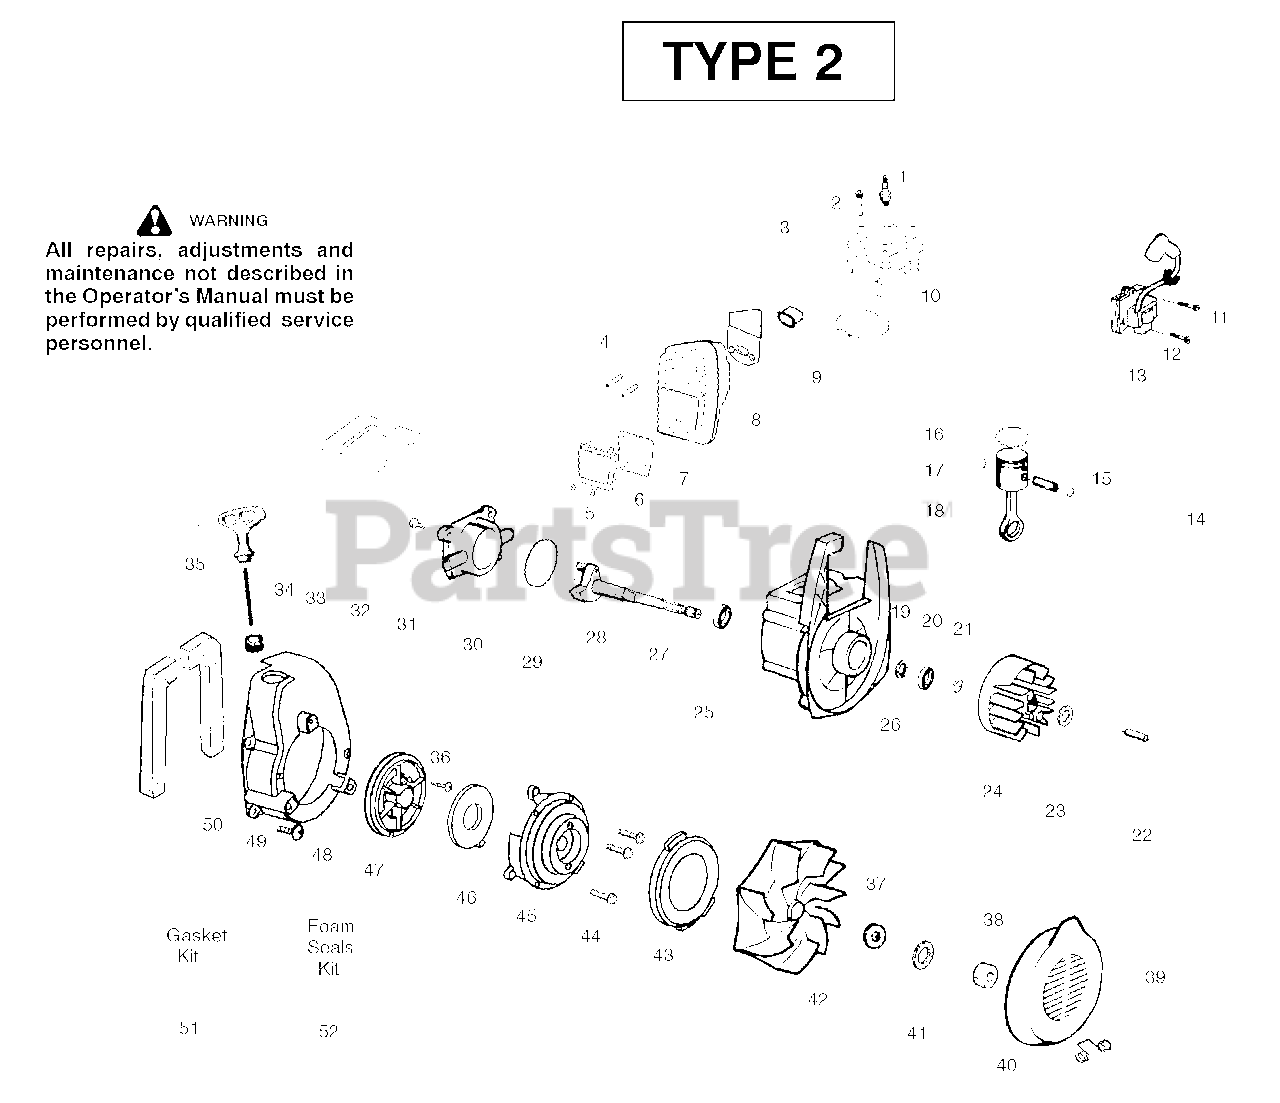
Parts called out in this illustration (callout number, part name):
1	Spark Plug (RCJ-6Y)
3	Insulator-Heat
4	Screw-Muffler-Internal
6	Kit-Spark Screen
7	Kit-Muffler
8	Gasket-Baffle (kit)
9	Gasket-Cylinder (kit)
10	Kit-Cylinder
11	Grommet-Ign. Module
12	Screw-Ignition Module
13	Ignition Module
14	Kit-Piston/Rod
15	Kit-Piston
16	Piston Ring
17	Retainer-Piston Pin
18	Assy-Connecting Rod
19	Seal-Crankcase
20	Bearing-Outer
21	Retainer Ring-C'chaft
22	Spacer-Flywheel
24	Assy-Flywheel
25	Assy-Crankcase/Crank shaft
26	Assy-Crankcase
27	Bearing-Inner
28	Assy-Crankshaft
29	O-ring-C/case (kit)
30	Cover-Crankcase
31	Screw
32	Foam-219mm (kit)
33	Eyelet-Flange
34	Kit-Rope
35	Handle-Starter
36	Screw-Rope
37	Washer-Belleville
39	Spring-Return Cover
40	Inlet Door
42	Kit-Impeller Assy.
43	Seal-Ring
45	Housing-Pulley
46	Spring-Starter
47	Kit-Starter Pulley
48	Fan Housing
49	Screw
50	Foam-182mm (kit)
51	Kit-Gasket
52	Kit-Foam Seals
